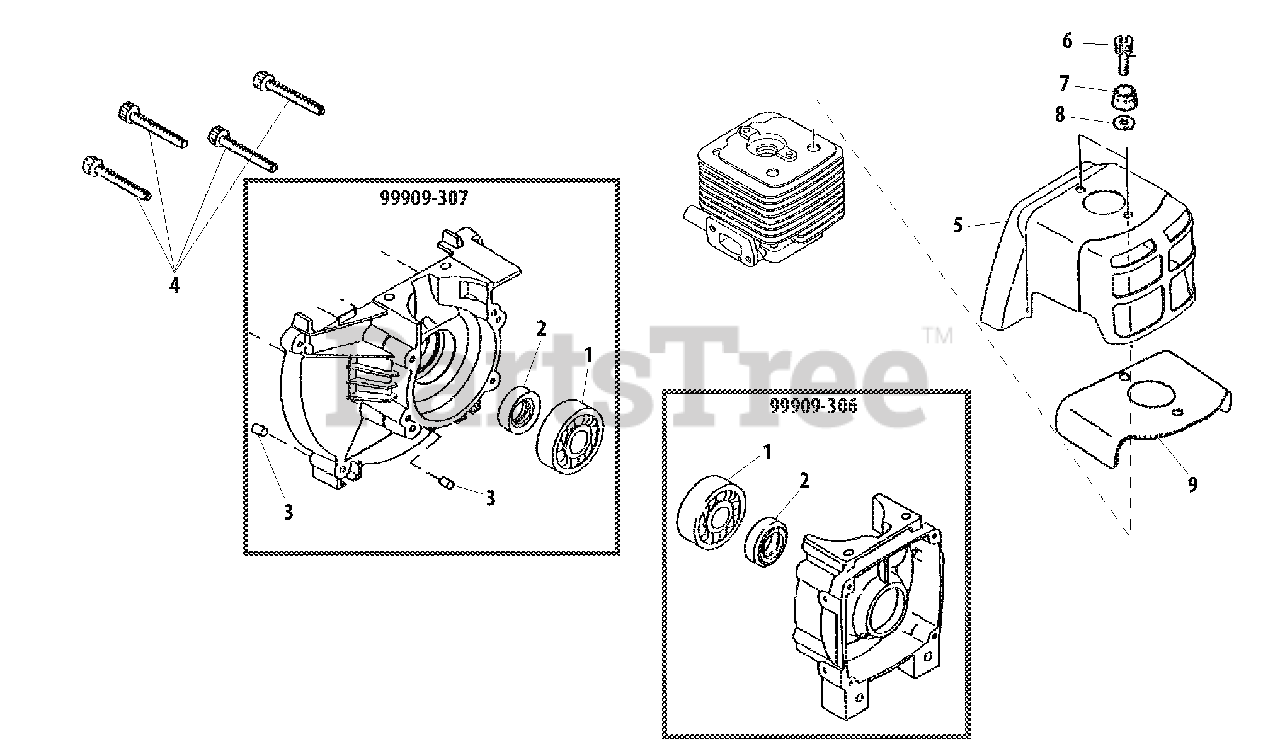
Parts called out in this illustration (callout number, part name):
1	BEARING, BALL 6202C3
2	SEAL, OIL 16
3	PIN, LOCATING 5×10
4	BOLT 5×30
5	COVER, ENGINE
6	BOLT M5×14
7	COVER
8	WASHER
9	SHIELD, HEAT
99909-306	CRANKCASE ASSY - REAR
99909-307	CRANKCASE ASSY - FRONT
